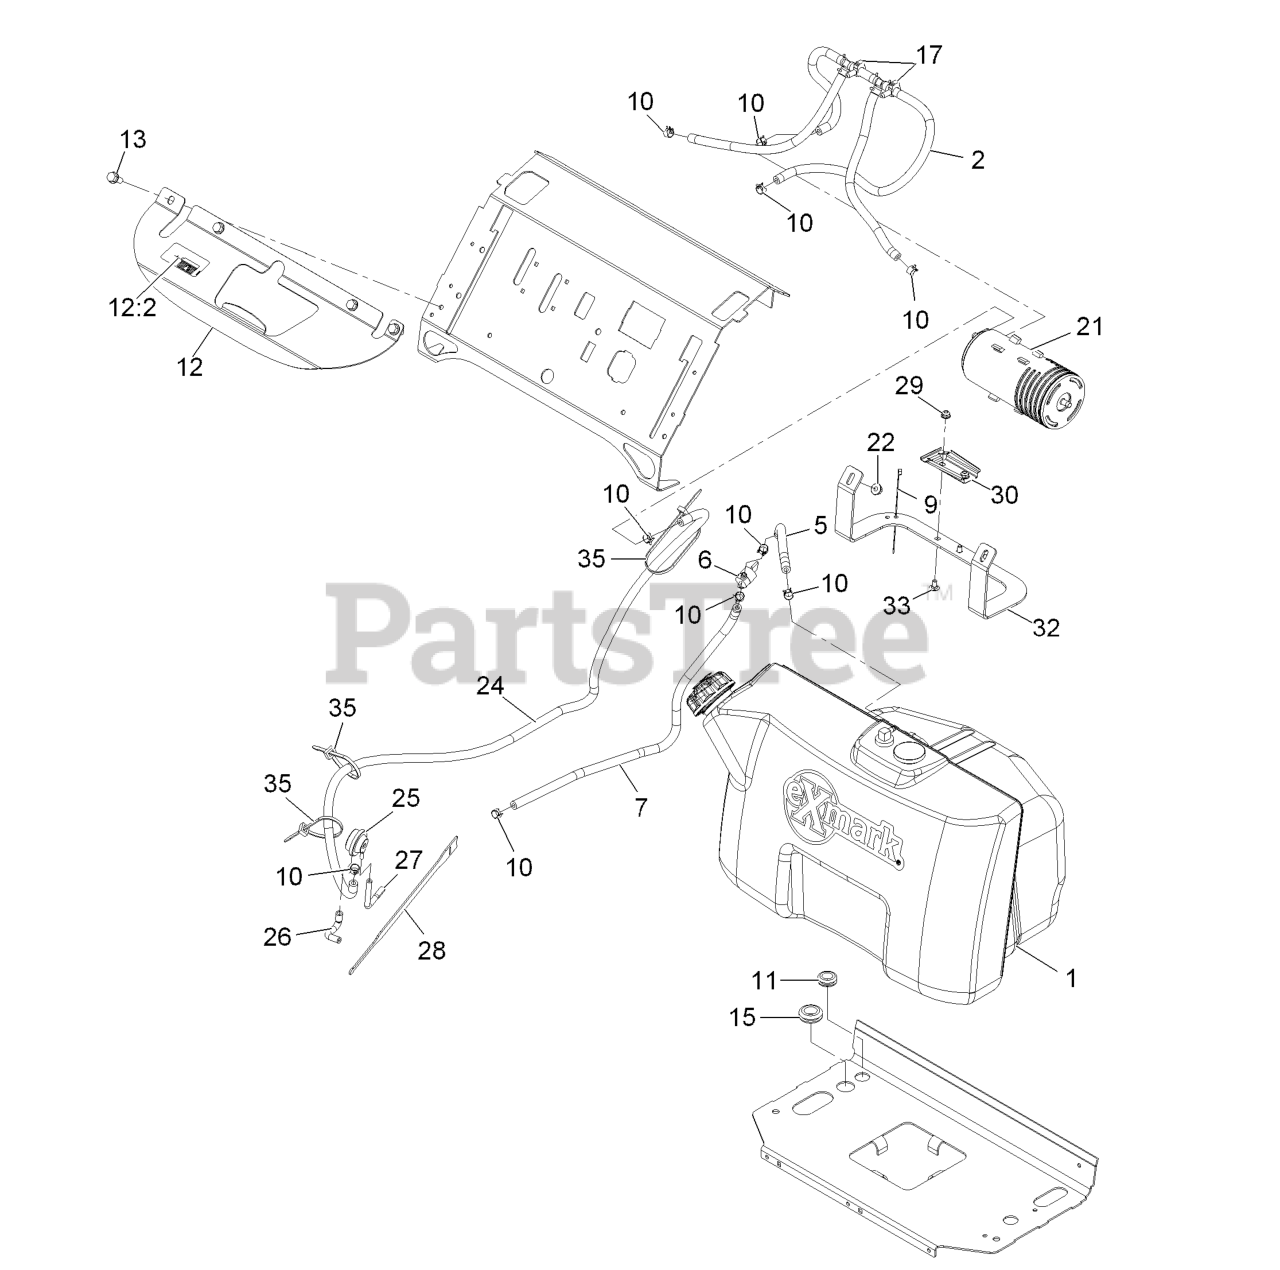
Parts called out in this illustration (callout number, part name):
2	VENT ASM
5	HOSE-FUEL
6	VALVE-FUEL
7	HOSE-FUEL
9	TIE-CABLE
10	CLAMP-HOSE
11	GROMMET
12	BRACKET-TANK
12:2	DECAL-FILL, FUEL
13	SCREW-THD ROLL, HWH
15	GROMMET
17	CLIP-HARNESS
21	CANISTER-CARBON, 800CC
22	NUT-HF, NI
24	HOSE-FUEL
25	VALVE-CONTROL, VACUUM
26	HOSE-VENT, FORMED
27	HOSE-VENT, FORMED
28	STRAP-VELCRO, CABLE TIE
30	BRACKET-CANISTER, CARBON
32	BRACKET,CANISTER MOUNTING
33	SCREW-CARR
35	TIE-CABLE
